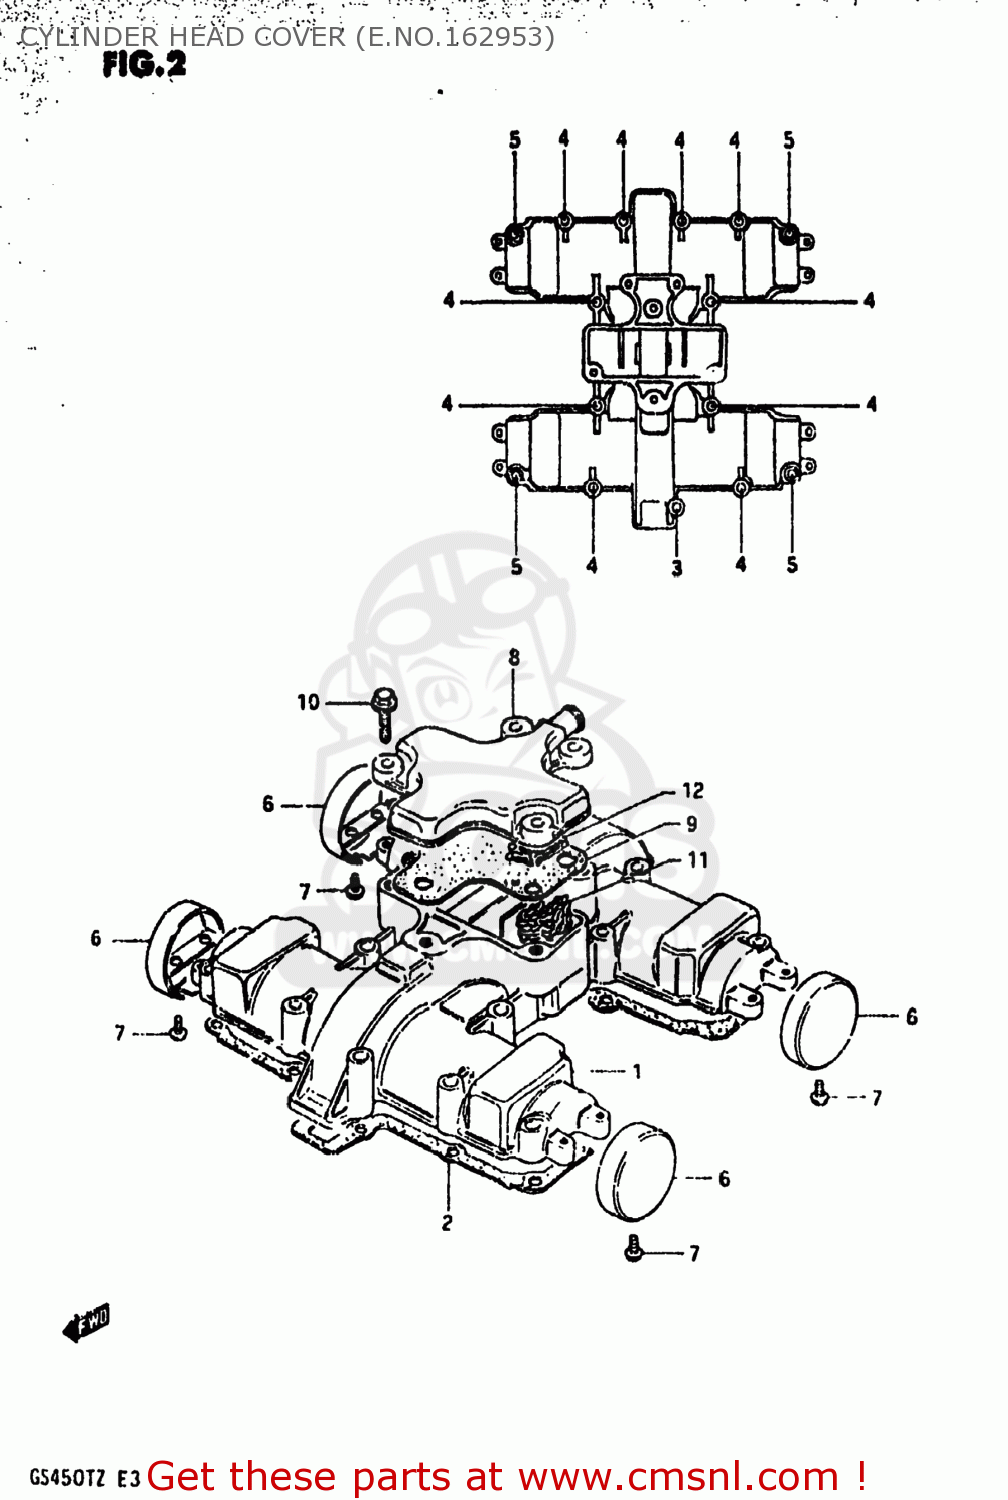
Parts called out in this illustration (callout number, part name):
1	COVER,CYLINDER HEAD
2	GASKET,CYLINDER HEAD COVER (MCA)
3	BOLT,UNDER
4	BOLT
5	BOLT
6	CAP,CYLINDER HEAD COVER
7	SCREW
8	COVER,BREATHER
9	GASKET (MCA)
10	BOLT,REAR
11	COVER,BREATHER
12	SEPARATOR,OIL BREATHER
